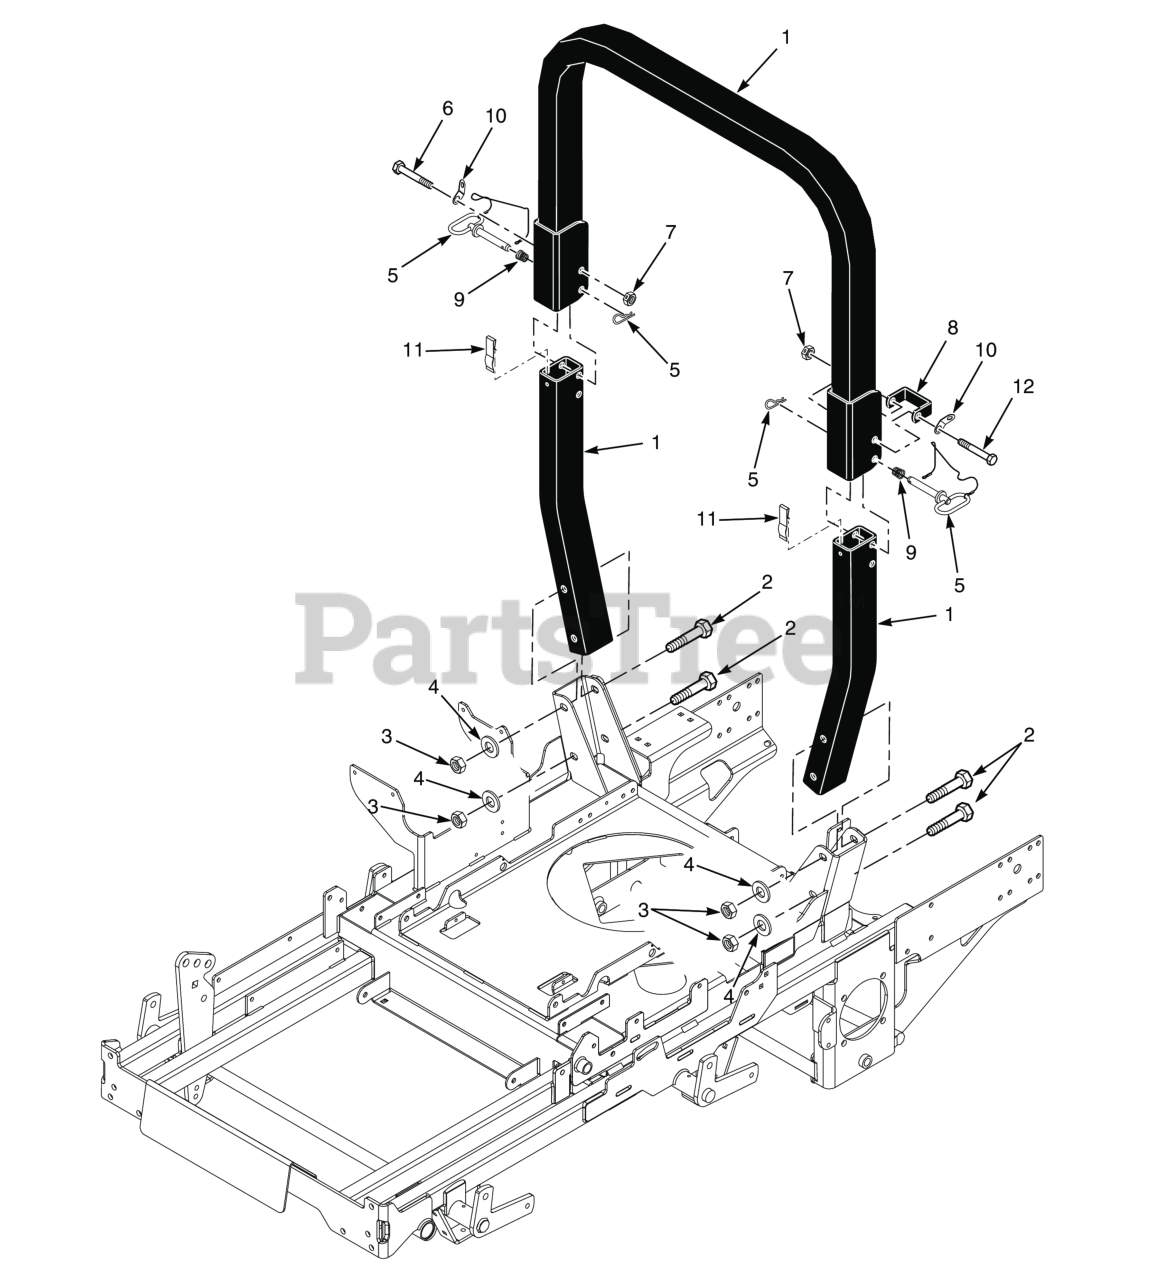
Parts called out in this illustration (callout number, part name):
1	STT, ROPS
2	Bolt, Hex Head 1/2-13 x 4-1/4"
3	Locknut, Hex 1/2-13 Center Lock
4	Flat Washer, 1/2 (.562 x 1.375 x .109)
5	Pin Assembly, ROPS Hinge
6	Bolt, Hex Head, 1/2-13 x 3-1/4"
7	HEX LOCKNUT, ELASTIC STOP, 1/2-13
8	Stop, ROPS
9	Spring, ROPS
10	Clip, ROPS
11	Spring, ROPS Anti-Rattle
12	Bolt, Hex Head 1/2-13 x 3-3/4"
